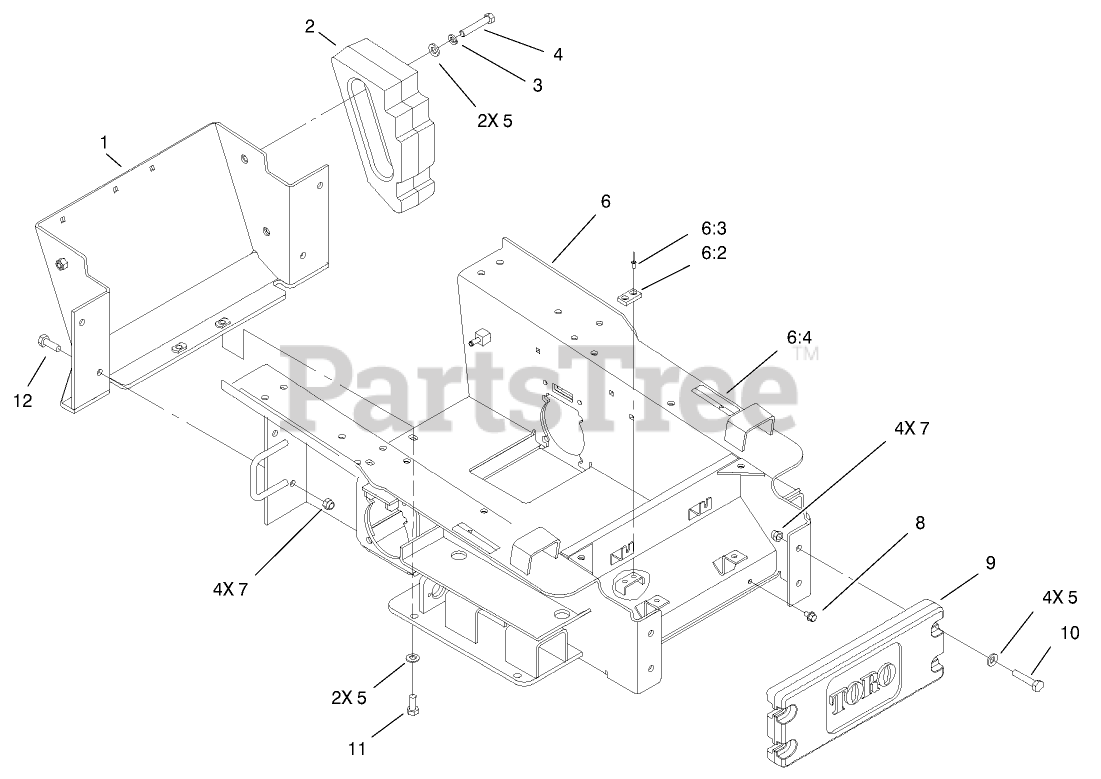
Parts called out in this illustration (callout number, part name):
1	REAR FRAME COVER ASM
2	COUNTERWEIGHT-REAR
3	WASHER-LOCK
4	SCREW-HH
5	WASHER-FLAT
6	MAIN CHASSIS ASM
6:2	PAD-SUPPORT
6:3	RIVET-POP
6:4	DECAL-PINCH
7	NUT-LOCK, NI
8	SCREW-HWHTF
9	COUNTERWEIGHT-FRONT
10	SCREW-HH
11	SCREW-HH
12	SCREW-HH
